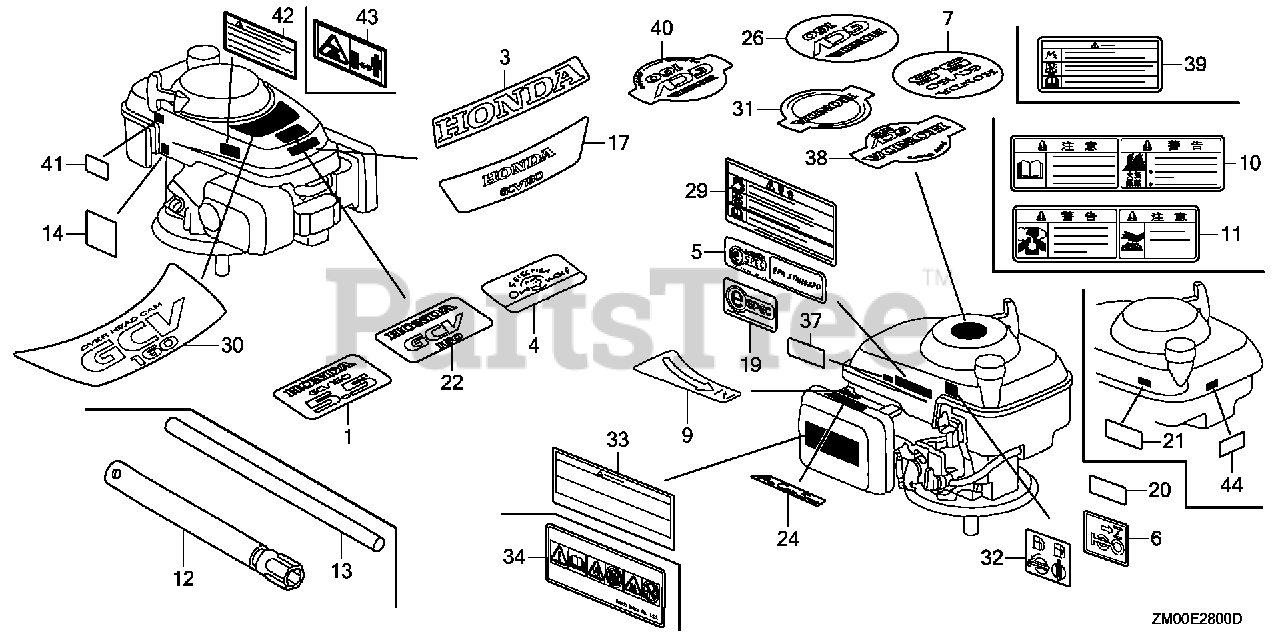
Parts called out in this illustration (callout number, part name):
6	MARK, CHOKE
30	MARK, EMBLEM (GCV160)
31	MARK, RECOIL COVER
32	MARK, FUEL PETCOCK CAUTION
33	MARK, OPERATOR CAUTION (ENGLISH)
37	LABEL, WARNING (NOT CERTIFIED FOR SALE)
